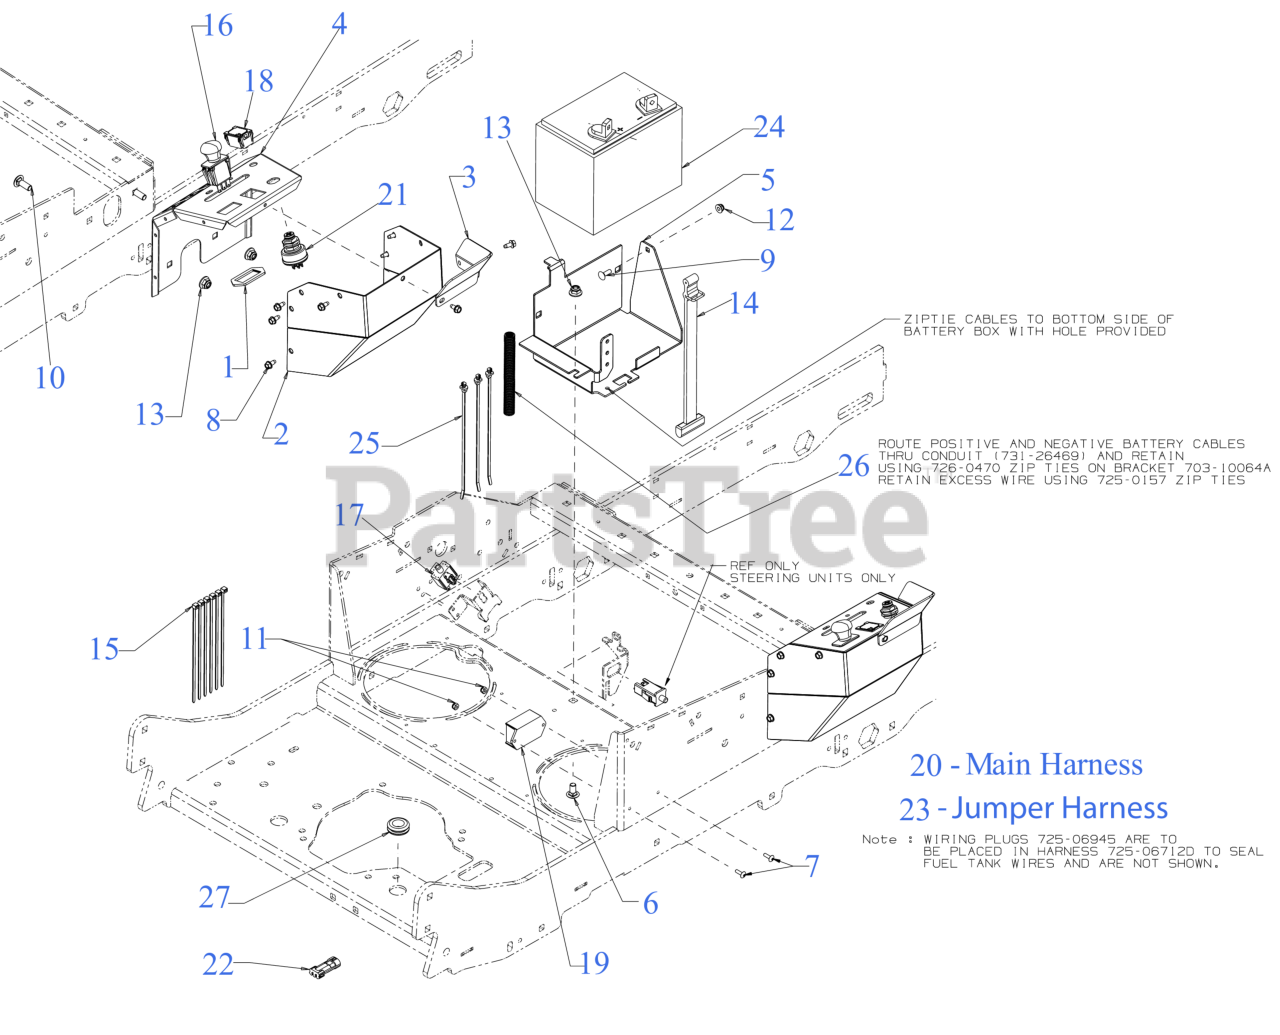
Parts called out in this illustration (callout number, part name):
1	BRACKET-PTO SWITCH
4	CONTROL POD (RH)
5	BATTERY MOUNT BRACKET
6	CARRIAGE BOLT 3/8-16 x .750 GR5
7	SCREW #10-24 x .62
8	SCREW 1/4-20 X.500
9	SCREW 1/4-20 x .75 GR5
10	CARRIAGE BOLT 3/8-16 x 1.00 GR5
12	FLANGE LOCK NUT
14	BATTERY RETAINER STRAP
15	7" CABLE TIE
16	PTO SWITCH (BLACK KNOB) TEXT SYM
17	3 POLE SWITCH ( NC-NO-NO)
19	CONTROL PANEL (SOFT CLUTCH)
20	WIRE HARNESS ASSEMBLY (KOH/KAW EFI)
21	KEY SWITCH (3 POSITION)
21	PRO-Z KEY SET
22	SEALED CAP ASSEMBLY
23	JUMPER HARNESS (W/RELAY)
24	BATTERY (230 CCA AGM U1-280)
25	CABLE TIE
26	CONVOLUTED CONDUIT 1"
27	RUBBER GROMMET
